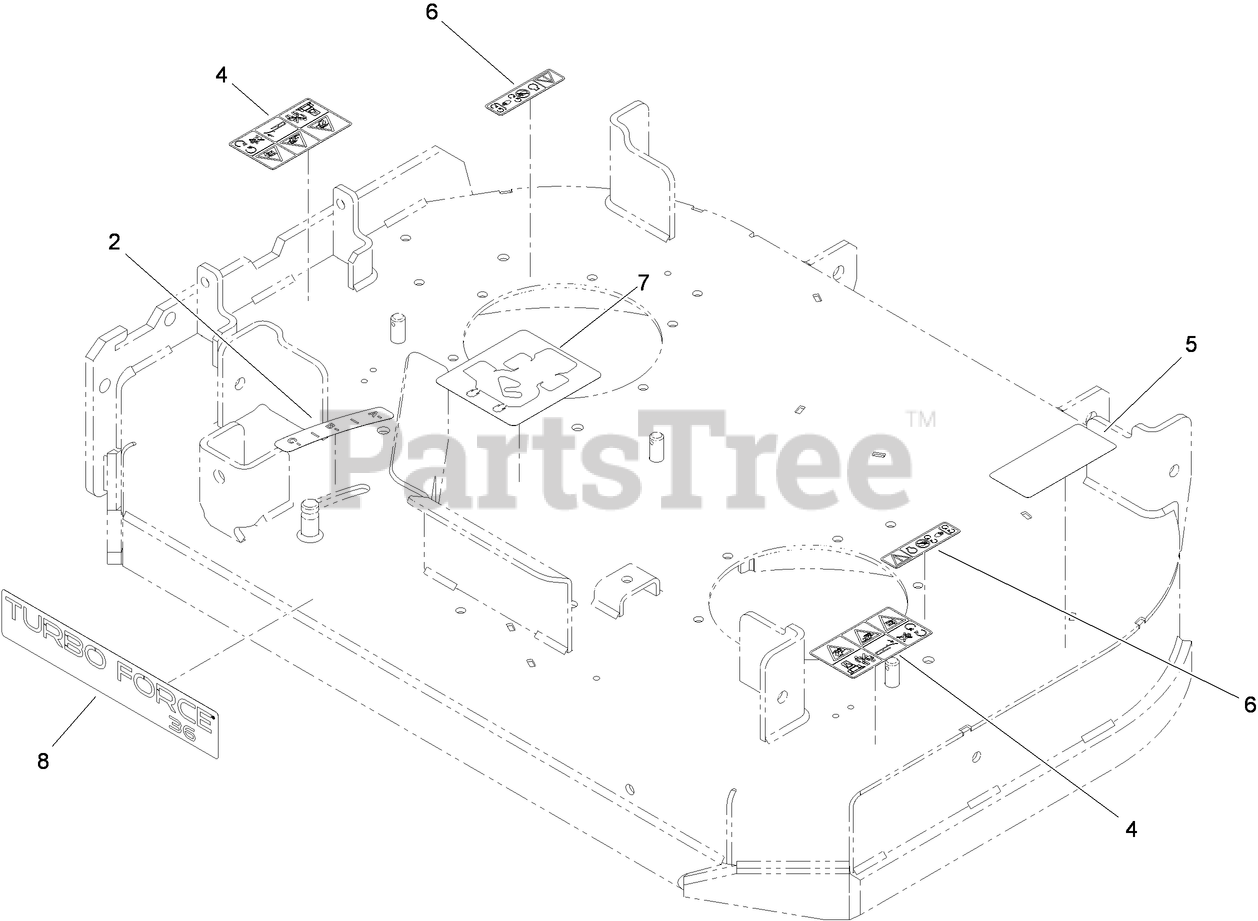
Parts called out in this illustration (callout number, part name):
2	DECAL-SETTING, BAFFLE
4	DECAL-DANGER
5	DECAL-TORQUE, BLADE BOLT
6	DECAL-DANGER
7	DECAL-ROUTING, BELT
